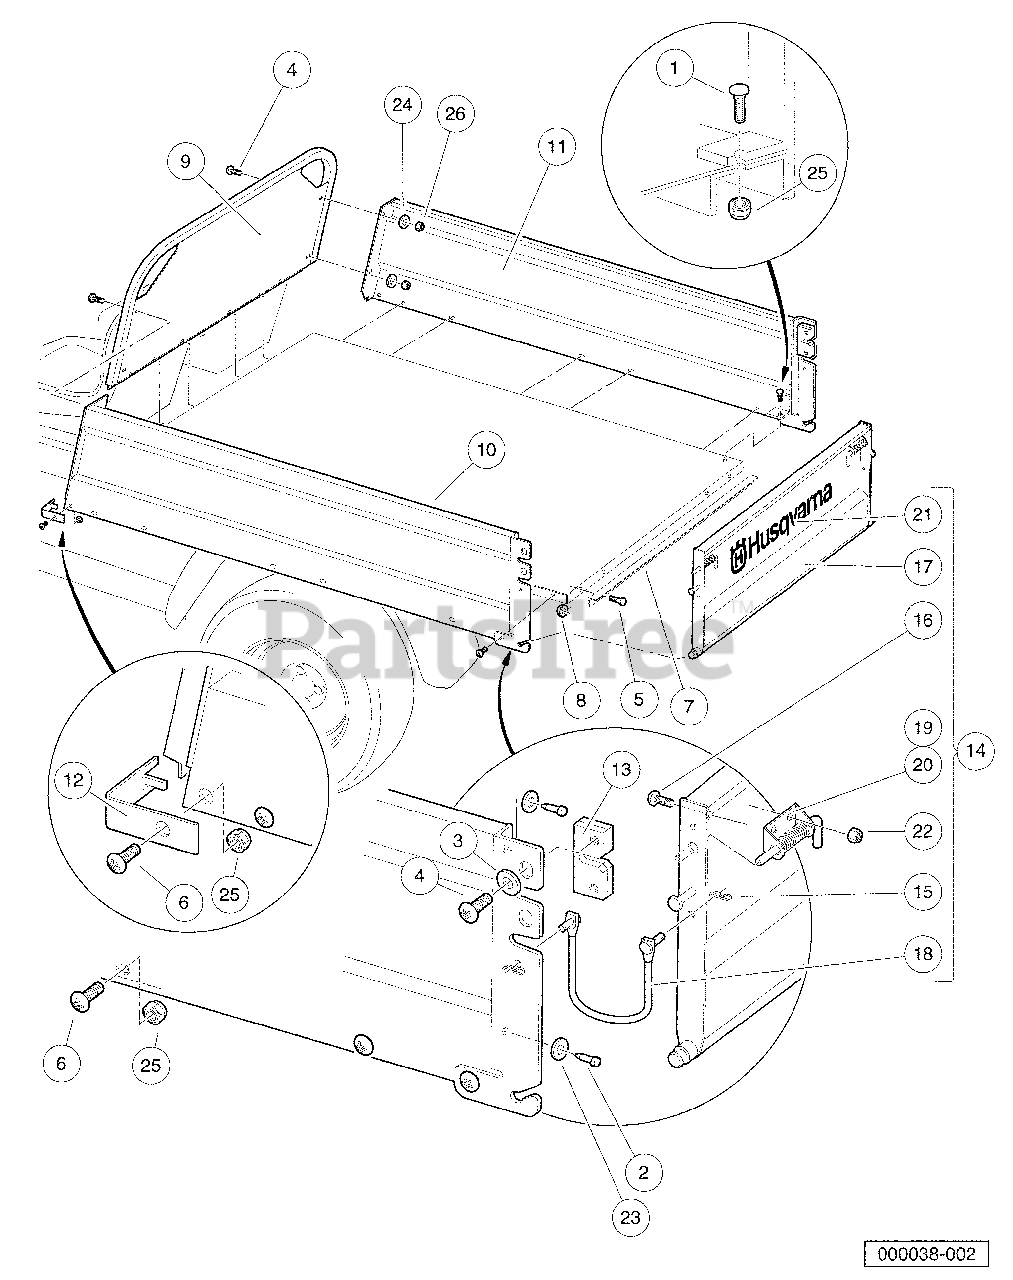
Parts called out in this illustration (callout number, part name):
1	Bolt, Carriage, 5/16-18 X 1.00
2	Bumper, Rubber
3	Washer, 1/4" Type B Flat
4	Screw, 1/4-20 X 0.75 Torx Truss-Head
5	Stud, Self-Clinching Flush Head
6	Screw, 5/16-18 X 0.88 Torx Truss-Head
7	Box Bed Tailgate Angle
8	Locknut, 5/16-18 Hex Flange
9	Front Panel Weldment
10	Left Panel Weldment
11	Right Panel Weldment
12	Front Corner Cap
13	Slam Latch
14	Assembly, Tailgate
15	Hair Pin Clip
16	Screw, 1/4-20 X 0.75 Torx Truss-Head
17	Tailgate, Weldment
18	Tether Assembly
19	Spring Latch Left
20	Spring Latch Right
21	Decal, Husqvarna, Tailgate
22	Locknut, 1/4-20 Nylon Insert.
23	Washer, Rubber, 3/8
24	Washer, 1/4 Type A Narrow Flat
25	Locknut, 5/16-18 Nylon Insert
26	Locknut, 1/4-20 Nylon Insert
